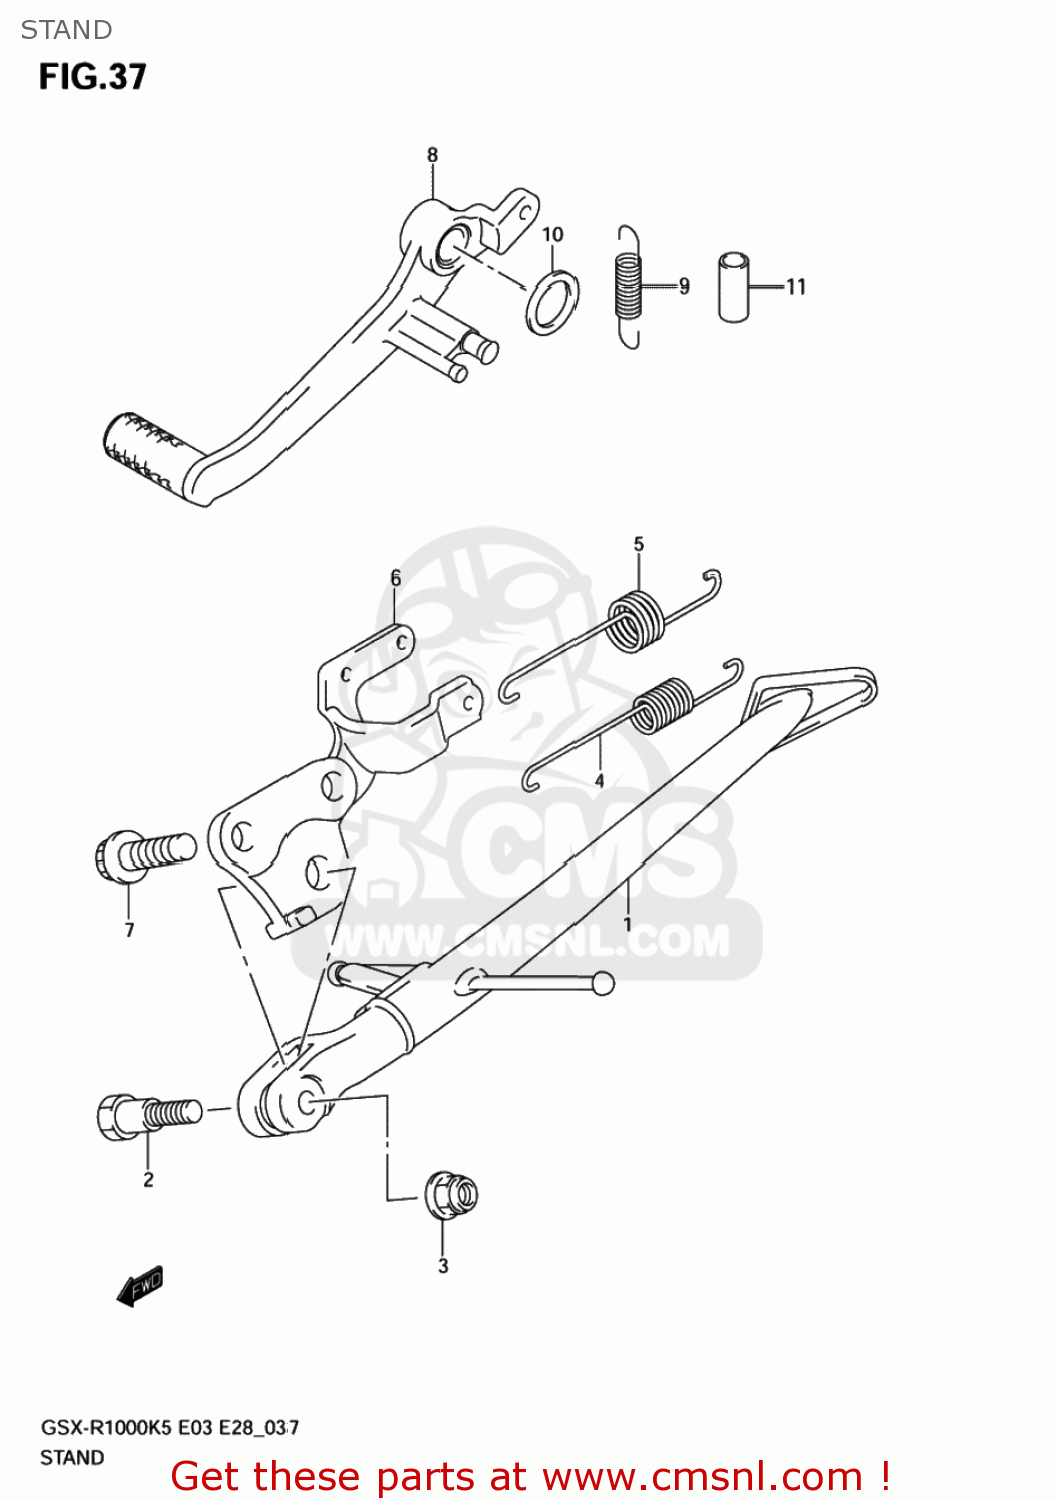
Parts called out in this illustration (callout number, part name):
1	STAND,PROP
2	BOLT(10X21)
3	NUT
4	SPRING
5	SPRING
6	BRACKET,PROP STAND
7	BOLT(10X28)
8	PEDAL,BRAKE
9	SPRING
10	WASHER(18X24X1)
11	HOSE(11X15X600)
